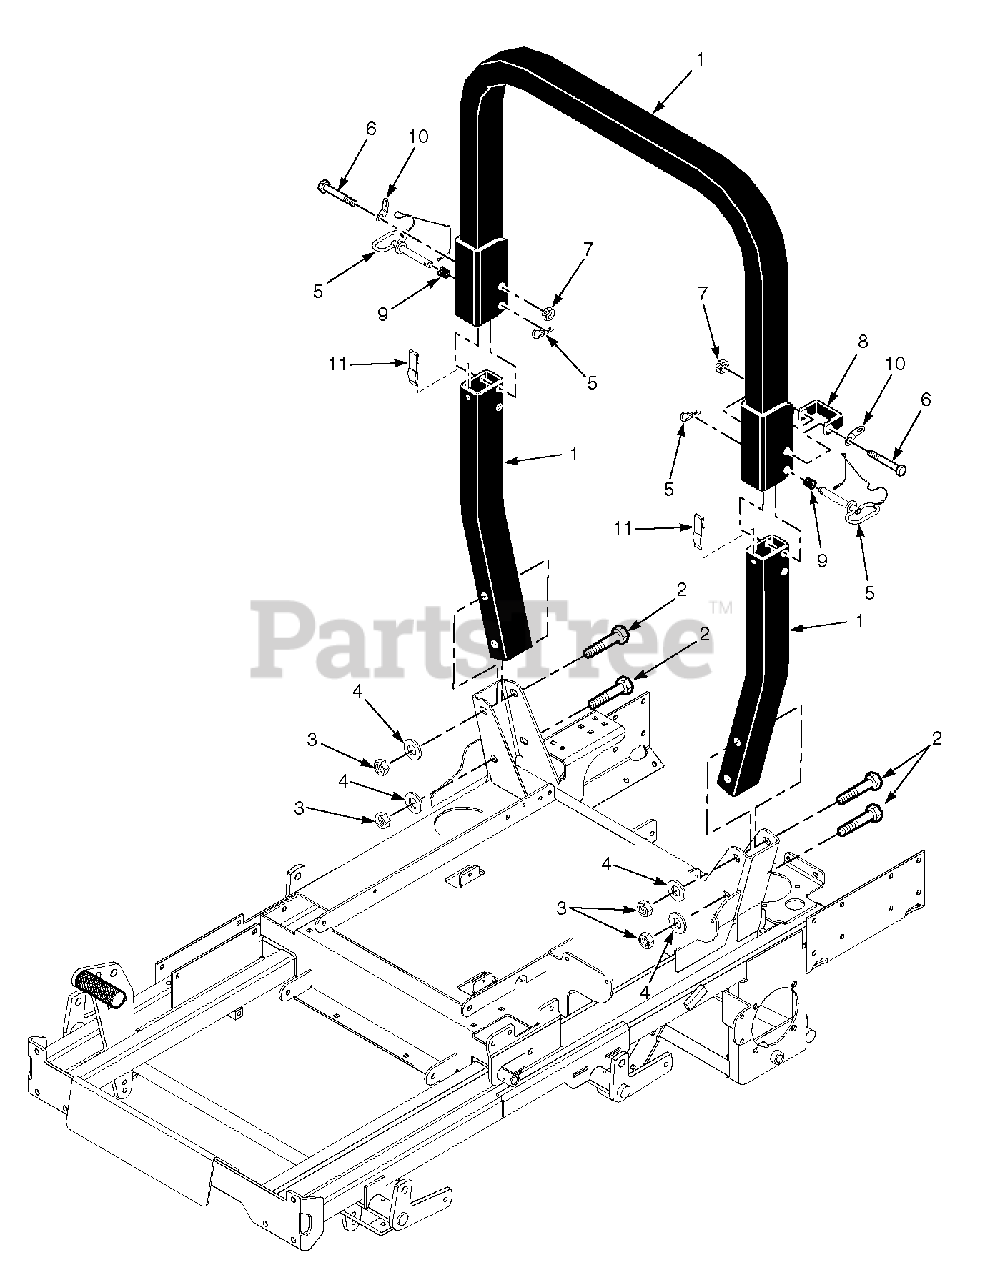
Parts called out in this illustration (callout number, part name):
1	STT, ROPS
2	Bolt, Hex Head 1/2-13 x 4"
3	Nut, Center Lock 1/2-13
4	Flatwasher, 1/2-.562 x 1.375 x .109
5	Pin Assembly
6	Bolt, Hex Head 1/2-13 x 3-3/4"
7	Nut, Center Lock 1/2-13
8	Stop Bracket, ROPS
9	Spring, ROPS
10	Clip, ROPS
11	Spring Clip, ROPS
